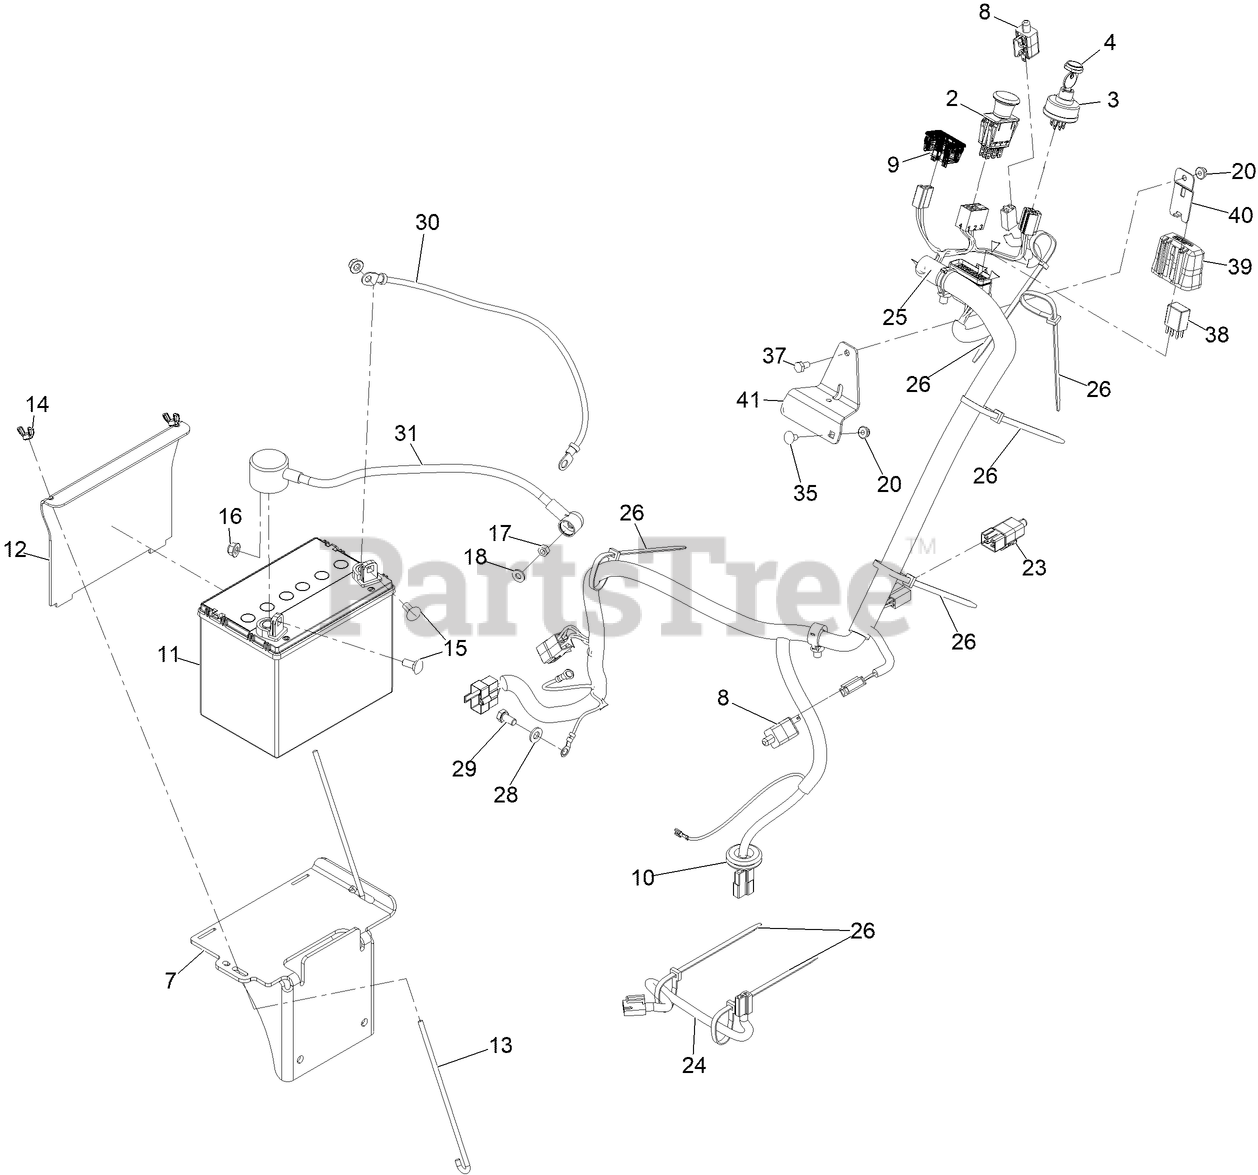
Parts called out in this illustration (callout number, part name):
2	SWITCH-PTO
3	SWITCH, KEY START
4	NUT-SWITCH, IGNITION
7	WELD, BATTERY MOUNT
9	METER-HOUR
10	GROMMET
11	Battery- Wet, 12V, 300 CCA
12	BRACKET, BATTERY HOLD DOWN
13	BOLT-HOLDDOWN
14	WINGNUT
15	BOLT-CARR
16	NUT-HF, NI
17	NUT-HEX
18	WASHER-FLAT
23	SWITCH, 2 POLE
24	HARNESS-CLUTCH PIGTAIL
25	HARNESS-WIRING
26	TIE-CABLE
28	WASHER-PLAIN
29	SCREW-HH
31	ASM,POSITIVE BATTERY CABLE
35	SCREW-CARR
37	SCREW-HH
38	RELAY-MICRO 280, SPDT
39	COVER-BLOCK, FUSE
40	CLIP-MOUNTING
41	BRACKET-MOUNTING, FUSEBLOCK
